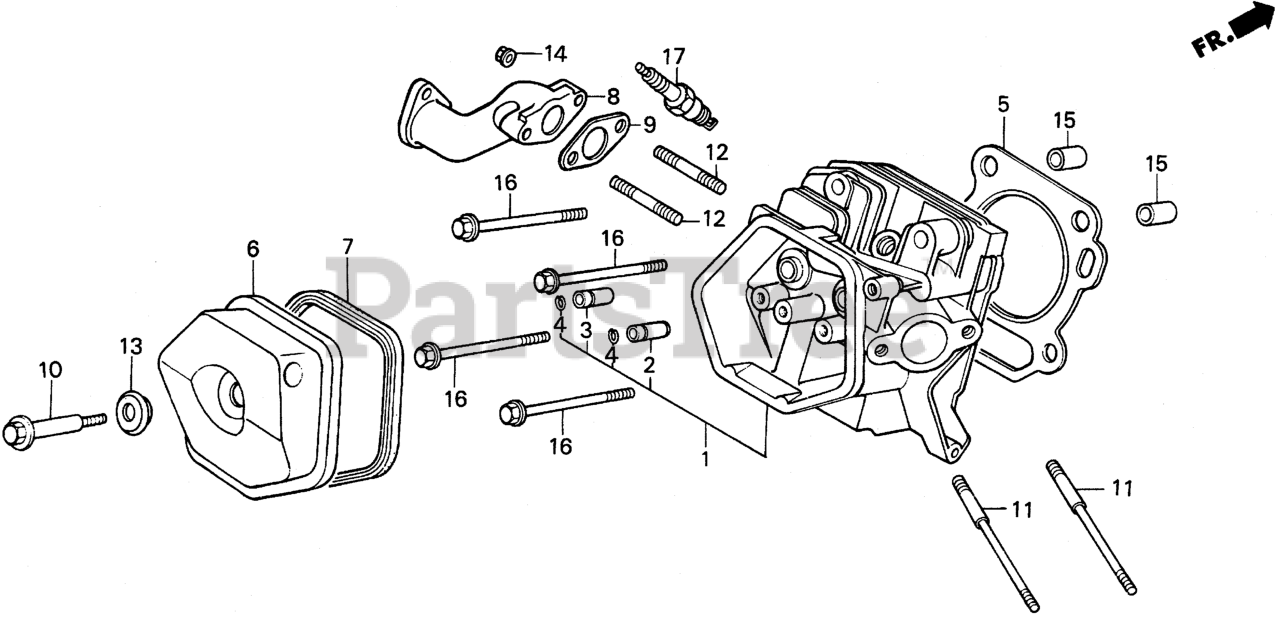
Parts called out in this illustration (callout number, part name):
1	CYLINDER HEAD
2	GUIDE, VALVE (OVER SIZE)
4	CLIP, VALVE GUIDE
5	GASKET, CYLINDER HEAD
6	COVER, HEAD
7	GASKET, CYLINDER HEAD COVER
9	GASKET, EX. PIPE Use up to Engine SN 2949254.
9	GASKET, EX. PIPE (WACKER)
10	BOLT, HEAD COVER
11	BOLT, STUD (8X98)
12	BOLT, STUD
13	WASHER, HEAD COVER
14	NUT, FLANGE (8MM)
15	PIN A, DOWEL (12X20)
16	BOLT, FLANGE (10X80)
17	SPARK PLUG (BPR5ES) (NGK)
17	SPARK PLUG (W16EPR-U) (DENSO)
